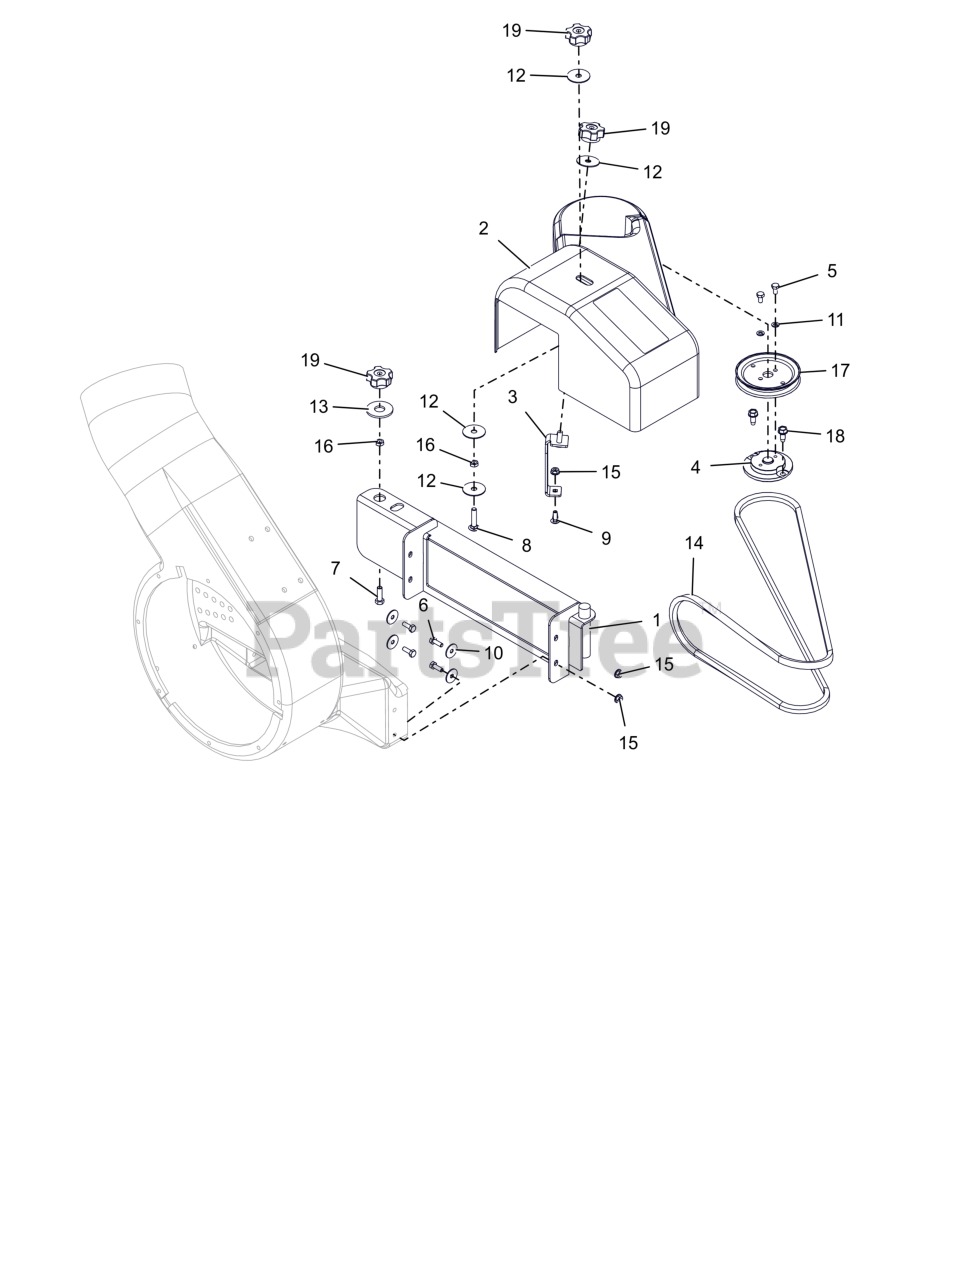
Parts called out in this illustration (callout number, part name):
1	WLDMT, PUMP MOUNTING (BLACK)
2	COVER, BAGGER BELT -W/DECAL
3	WLDMT, BAGGER BELT COVER BRKT
4	ADAPTOR, BAGGER SHEAVE
5	BLT,HEX .25-20X.50 G5 ZCC
6	BLT, HEX .25-20X.75 G5 ZCC
7	BLT, HEX .31-18X1.00 G8 ZCC
8	BLT,RHSN .31-18X1.50 G5 ZCC
9	BLT, RHSN .25-20X.750 G5 ZCC
10	WSHR,FLT .281X1.000X.063 ZCC
11	WSHR,LK-REG .250X.062 ZCC
12	WSHR,FLT .380X1.50X.062 ZCC
13	WSHR,FLT .688X1.75X.134 ZCC
14	V-BELT, HA-WRAPPED
15	NUT-LK-TOP-FLG .250-20 GF ZCC
16	NUT-JAM .312-18 G2 ZCC
17	SHEAVE, SPINDLE (4.25 HA )
18	SCR,TAP .312-18X.75 HWH TR ZCC
19	KNOB-CLAMPING, .312-18 NYLOC
